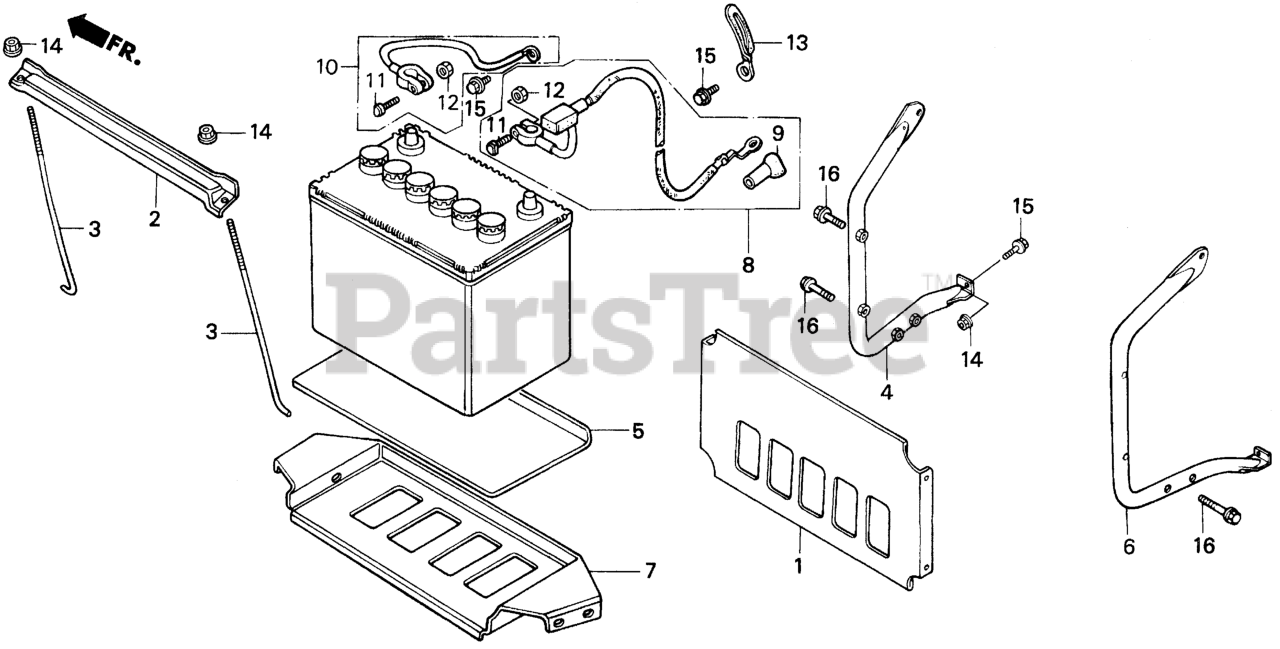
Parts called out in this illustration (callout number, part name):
1	PLATE, BATTERY GUARD
2	PLATE, BATTERY SETTING
3	BOLT, BATTERY SETTING (220MM)
4	GUARD, FR. BATTERY
5	PLATE, BATTERY Use from Frame SN 1127014.
6	GUARD, RR. BATTERY
7	BASE, BATTERY TRAY
8	CABLE ASSY., STARTING
9	COVER, STARTER MOTOR TERMINAL
10	CABLE ASSY., GROUND
11	BOLT, BATTERY TERMINAL (SUMITOMO)
11	BOLT, BATTERY TERMINAL
12	NUT, BATTERY TERMINAL (SUMITOMO)
13	CLIP, HEAD
14	NUT, FLANGE (6MM)
15	BOLT, FLANGE (6X12) Use up to Engine SN 1543277.
16	BOLT, FLANGE (6X28)
NI	BATTERY (GR.51) (NOT AVAILABLE) (MSDS)
